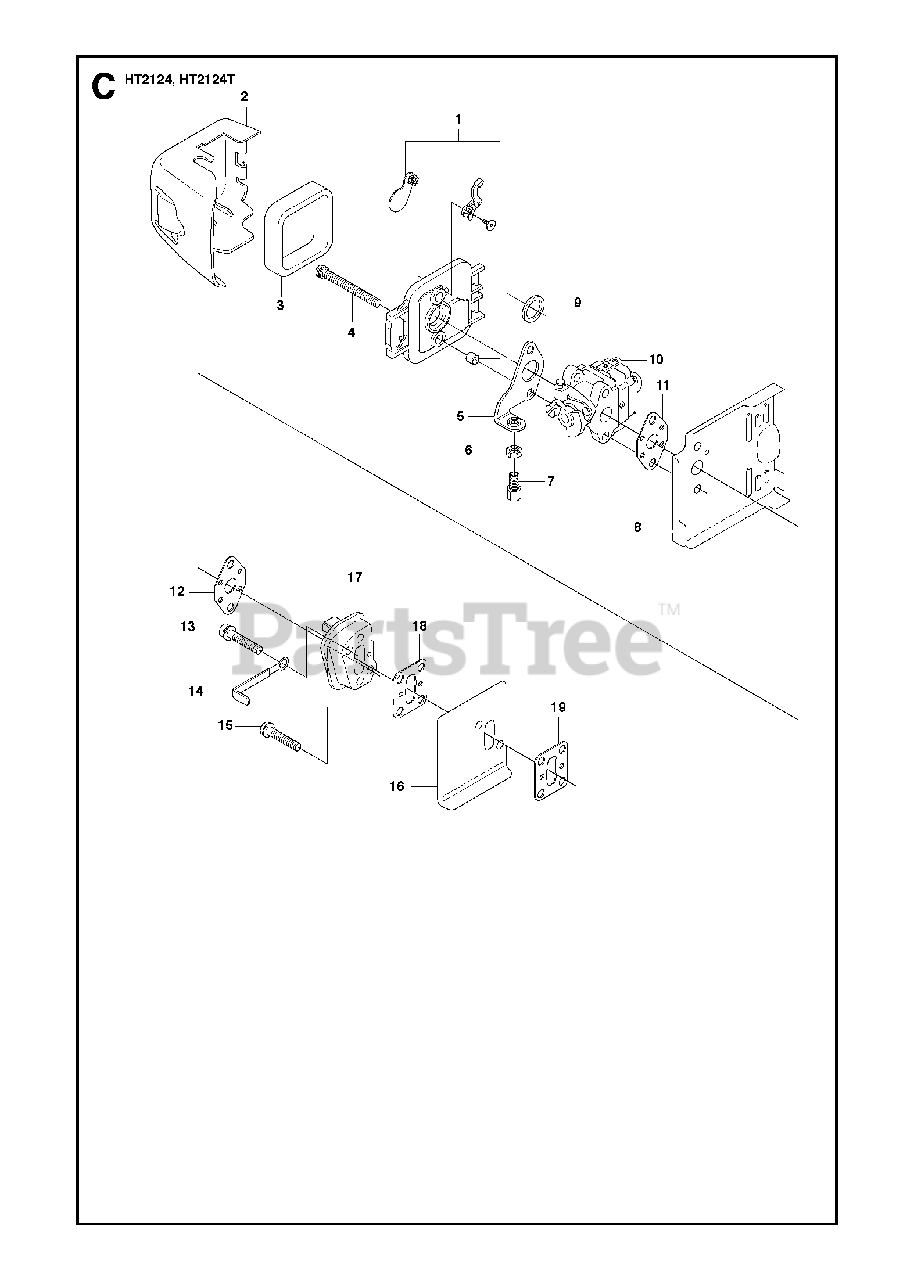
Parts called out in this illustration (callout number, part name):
1	FILTER COVER
3	FILTER ELEMENT
10	CARBURETOR
17	INSULATOR
